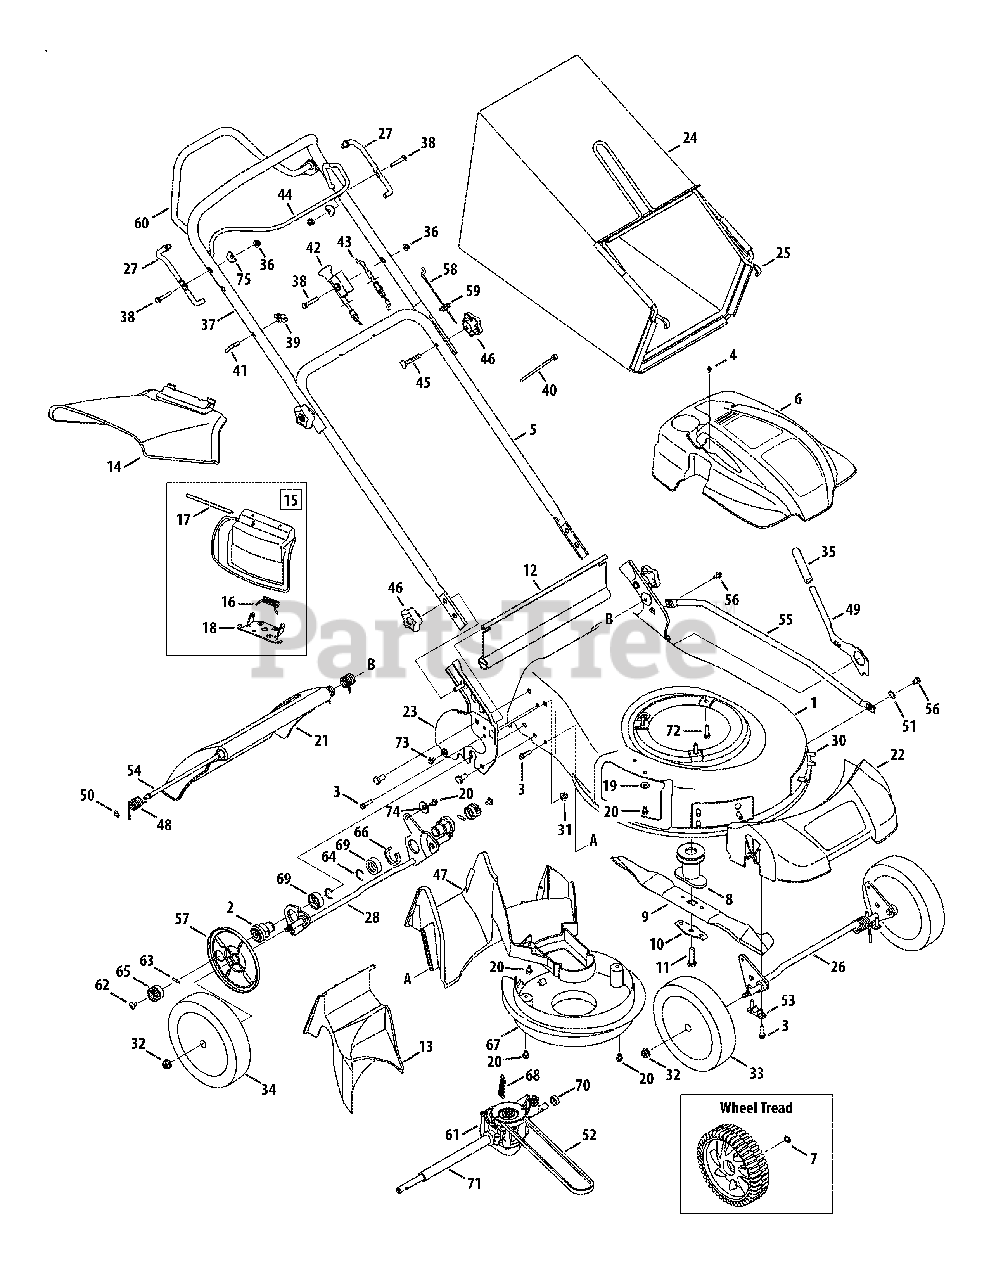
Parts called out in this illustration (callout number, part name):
2	Transmission Support Bearing
3	Screw, 1/4-15 x 1.000
4	Screw, HL, #12-16 x 1.00
6	Engine Shroud
7	Washer, Wave, .510 x .750 x .017
8	Blade Adapter
9	Mulching Blade
10	Blade Bell Support
11	Screw, 3/8-24 x 1.50
12	Trailing Shield
13	Rear Mulch Plug
14	Side Discharge Chute
15	Mulch Plug (Incl. 16-18)
16	Torsion Spring
17	Hinge Pin
18	Chute Deflector Adapter
19	Belleville Washer
22	Front Cover
23	Handle Bracket - RH
23	Handle Bracket - LH
25	Grass Bag Frame
26	Front Bracket Assembly
27	Drive Control Pivot Rod - LH
27	Drive Control Pivot Rod - RH
28	Self Propelled Bracket Assembly
29	Hhcs, 5/16-18 x .625
30	Screw, 5/16-14 x .750
31	Nut, Flange Lock, 5/16-18
32	Nut, Flange Lock, 3/8-16
33	Front Wheel
34	Rear Wheel
35	Foam Grip
36	Nut, Flange Lock, 1/4-20
37	Upper Handle
38	Screw, 1/4-20 x 1.50
40	Cable Tie
41	Rope Guide
42	Choke Cable
43	Control Cable
44	Blade Control
45	Bolt Carriage, 5/16-18 x 2.0
46	Star Knob
47	Rear Baffle
48	Door Torsion Spring - RH
48	Door Torsion Spring - LH
49	Spring Lever
51	Washer, Wave, .385 ID x .598 OD
53	Bushing, Lock, .505 Dia. X .62
54	Rear Door Pivot Rod
55	Cross Bracket
56	Scr., Shldr., 1/4-20 x .50
57	Wheel Dust Cover
58	Drive Cable
60	Drive Control
61	Transmission
62	Screw, 1/4-20 x .390
63	Dowel Pin
64	Retainer Ring
65	Spur Gear - RH
65	Spur Gear - LH
66	Spacer, Clip
67	Engine Baffle
68	Extension Spring, .429OD x 2.515
69	Bearing Support Spacer
70	Sleeve Spacer, .550ID x .340 Lg.
71	Sleeve Spacer, .550ID x 7.97 Lg.
72	Screw, 3/8-16 x 1.00
73	Screw, #10-16 x .500
74	Washer, Bell, .340 x .872 x .060
75	Washer, Saddle
